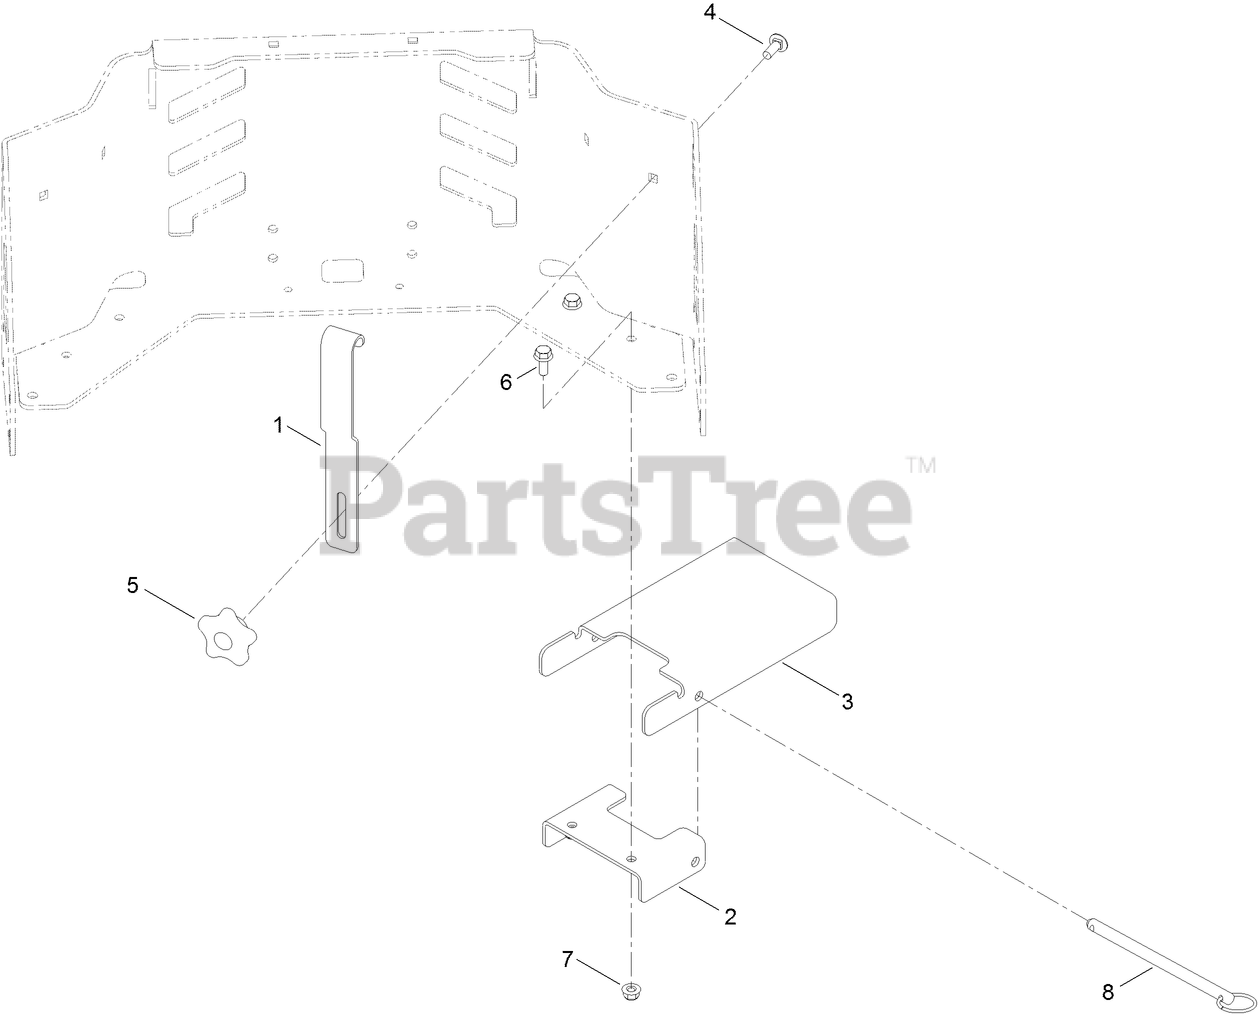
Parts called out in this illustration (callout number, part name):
1	KEEPER-BUCKET
4	BOLT-CARR
5	KNOB-HANDLE
6	SCREW-HHF
7	NUT-HF, NI
8	PIN - LOCKING
